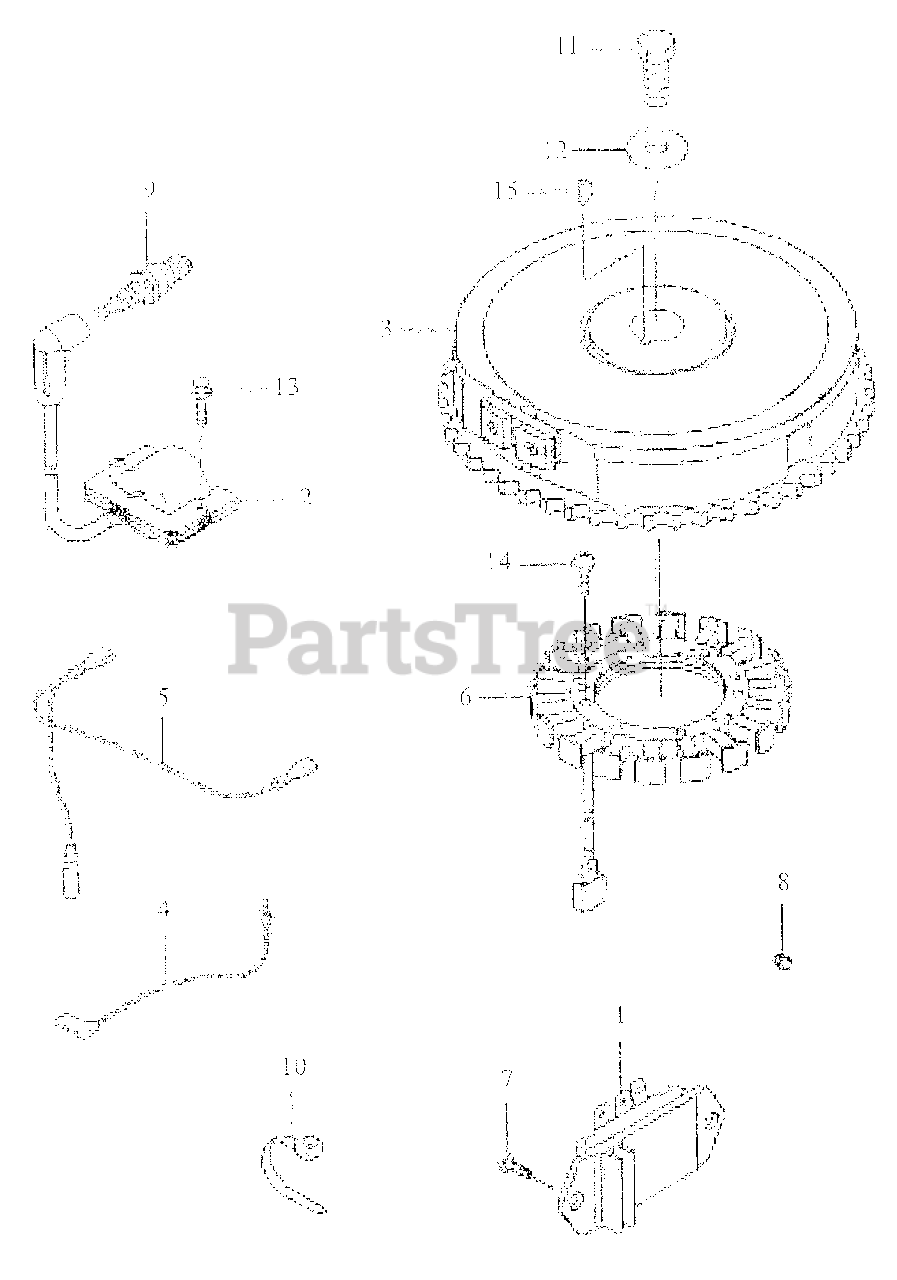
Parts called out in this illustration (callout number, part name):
1	Regulator, Voltage
2	Coil, Ignition
6	Coil, Charging
9	Spark Plugs
11	Bolt, 12 x 30
13	Bolt, Flange
14	Screw Pan Head
15	Key, Woodruf
